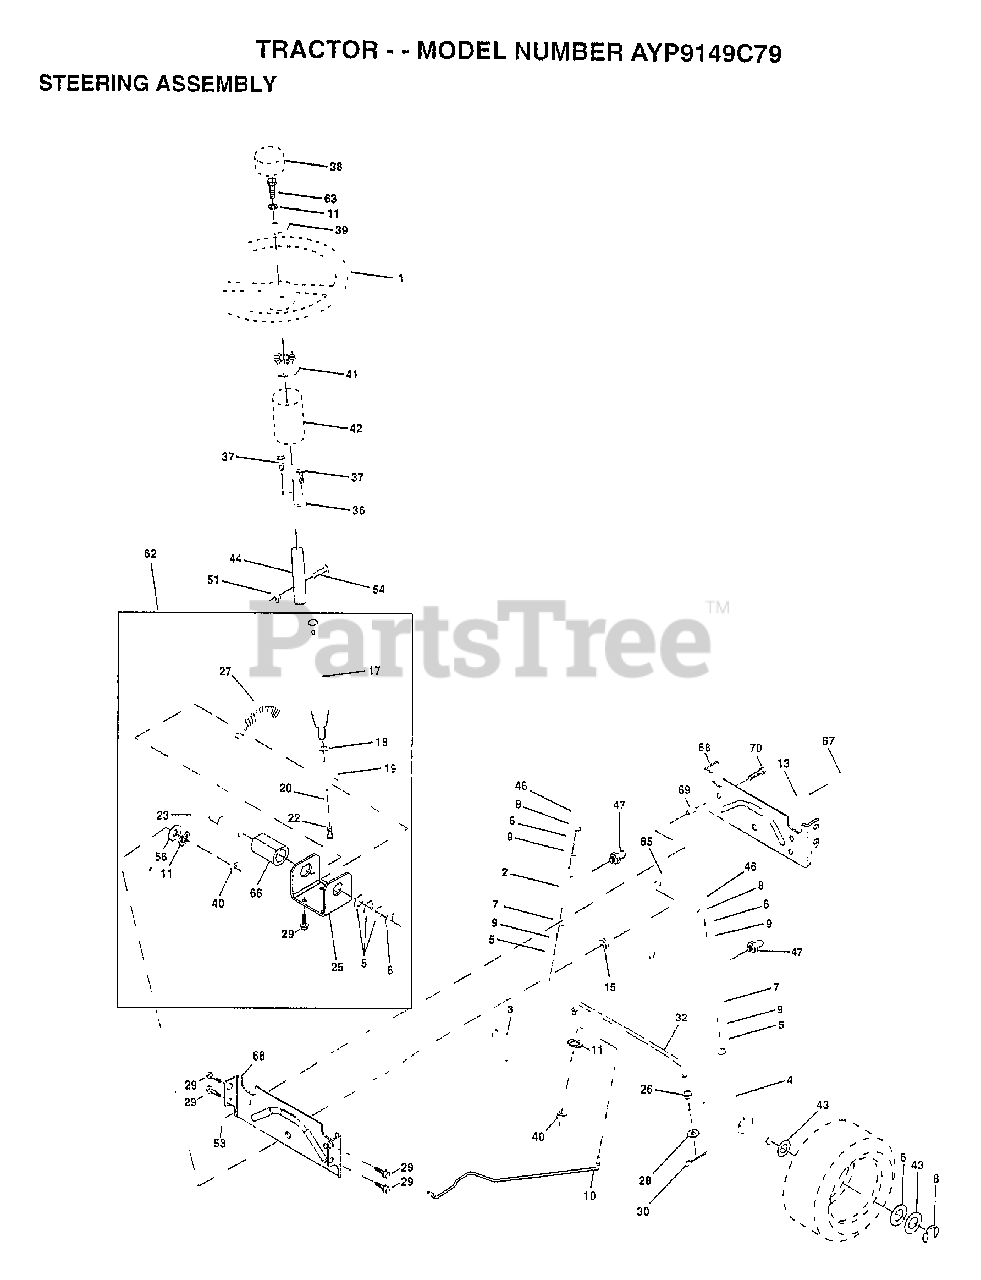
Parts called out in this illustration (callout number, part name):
1	WHEEL STR AYP BLK
2	AXLE ASM
3	SPINDLE.ASM.LH
4	"SPINDLE ASM,RH"
5	WASHER .T
6	WASHER
7	WASHER
8	RING
9	COL. SRTG. BEAR.
10	DRAGLINK-STAMPED
11	LOCKWASHER
13	BEARING AXLE
15	"NUT-LOC,FLANGE LT"
17	SHAFT ASM STEERIN
18	THRUST WASHER
19	SUPPORT.SHAFT
21	LOCKWASHER
22	SCREW.SCKTHD.CAP
25	BRKT-STEERING
26	BUSHING.DRAGLINK
27	GEAR SECTOR
28	WASHER
29	SCREW
30	COTTER PIN
32	TIE ROD
36	BUSHING.STEERING
37	"SCREW-TT,10-32 FL"
38	CAP STEER AYP
39	WASHER T
40	GRIPCO NUT
41	ADAPTER LT
42	BOOT.STEER.PL
43	WASHER
44	EXT SHAFT STEERIN
46	CAP
47	ZERK M
51	NUT
54	BOLT
62	KIT STEERING ASM
63	BOLT
65	SPACER AXLE
66	"BEARING-ARM,PITMA"
67	BOLT
68	BRACE AXLE
69	"SPACER BRCAE,AXLE"
70	BOLT.HEX.3/8-16X2
